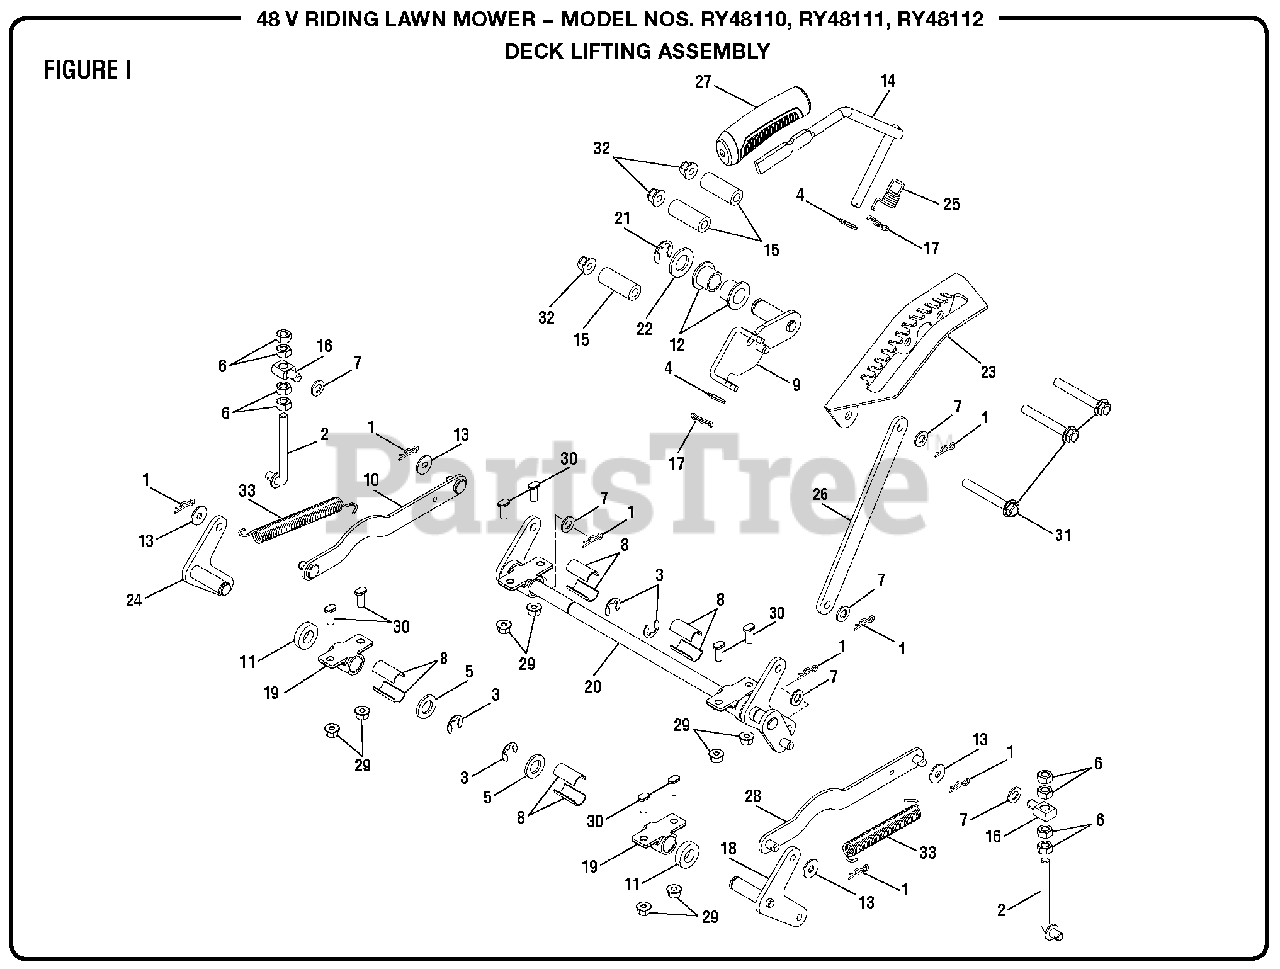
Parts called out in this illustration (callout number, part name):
1	Cotter Pin (10 mm)
2	Hanger Stud
3	E-Ring Clip (12 mm)
4	Washer (OD24 x ID13 x 2.5t)
5	Washer (OD30 x ID17 x 3t)
6	Nut (M10)
7	Washer (OD20 x ID10.5 x 2t)
8	Half Bushing Sleeve
9	Deck Lift Pivot Assembly
10	Right Linkage Assembly
11	Deck Lift Spacer
12	Pivot Plastic Sleeve
13	Washer (OD20 x ID10.5 x 2t)
14	Lever Rod
15	Spacer (10.5 x 20 x 51)
16	Hanger Stud Mount
17	Cotter Pin (12 mm)
18	Front Lifting Axle, Left
19	Frame Mount Hanger Bracket
20	Rear Lifting Axle
21	E-Ring Clip (15 mm)
22	Washer (OD37 x ID21 x 3t)
23	Detent Plate (4 mm)
24	Front Lifting Axle, Right
25	Torsion Spring
26	Deck Lift Lever Double Link
27	Decklift Handle
28	Linkage Assembly, Left
29	Flange Nut (M8)
30	Bolt (M8 x 25 mm, Flush Mount)
31	Flange Bolt (M10 x 75 mm, Hex Hd.)
32	Lock Nut (M10 x 1.5 mm)
33	Tension Spring (Deck)
